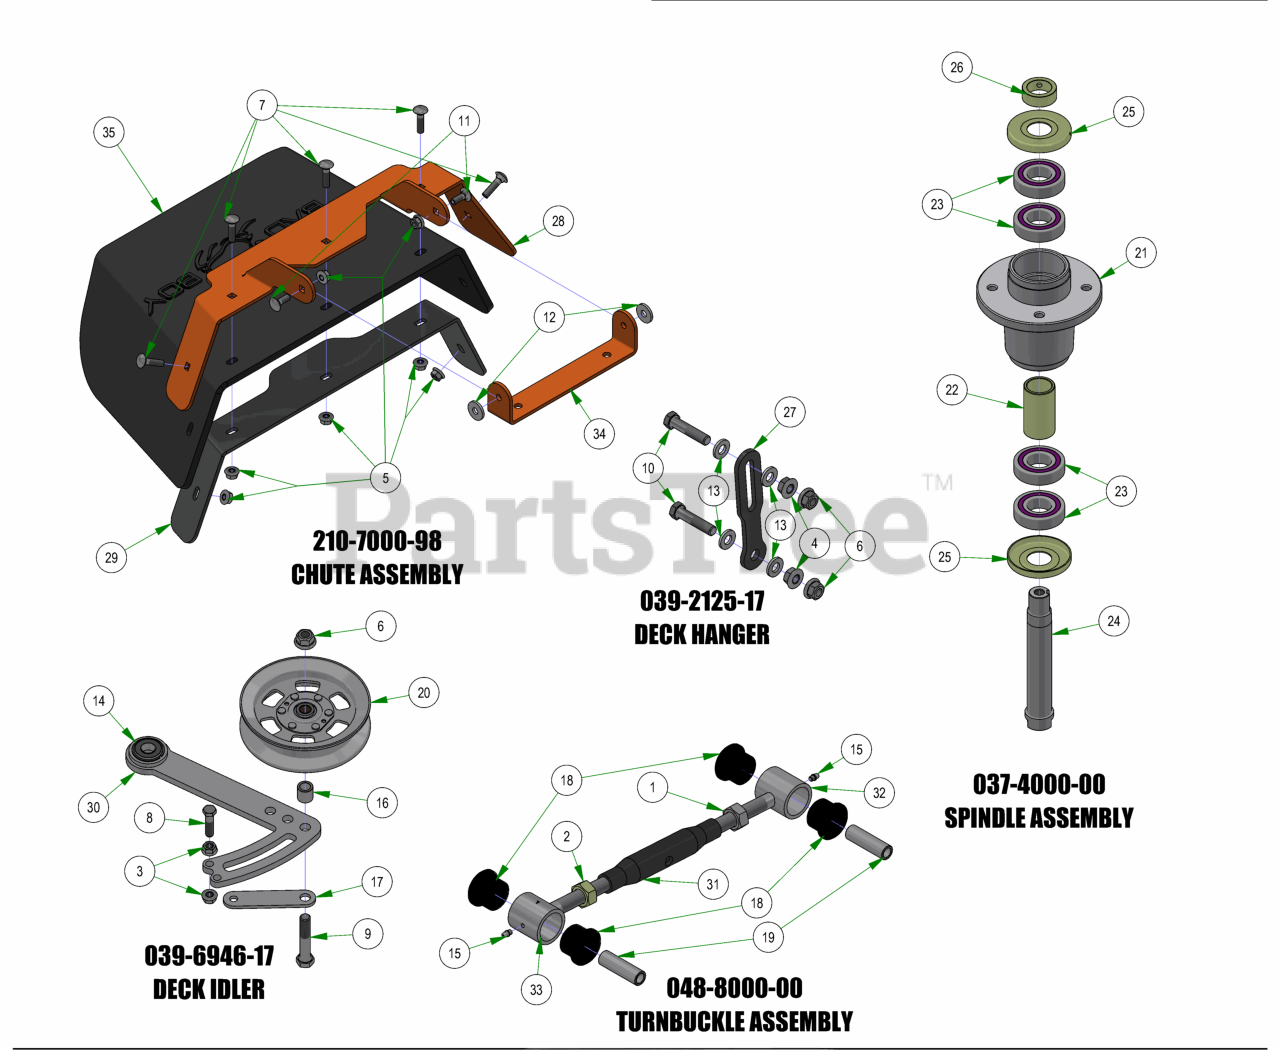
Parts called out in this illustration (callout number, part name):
1	Hex Nut M20-2.5
2	Hex Nut M20-2.5 Left Hand Threads Gold Plated
3	3/8-16 HEX SERRATED FLANGE NUT HARD/ZINC
4	1/2-13 HEX SERRATED FLANGE NUT HARD/ZINC
5	5/16-18 NYLON INSERT FLANGE LOCKNUT ZINC
6	1/2-13 NYLON INSERT FLANGE LOCKNUT ZINC
7	5/16-18 X 1-1/4 CARRIAGE BOLT ZINC
8	3/8-16 X 1-1/2 HEX CAP SCREW (GR.5) ZINC
9	1/2-13 X 2-3/4 HEX CAP SCREW (GR.5) ZINC
10	1/2-13 X 2-1/4 HEX CAP SCREW (GR.5) ZINC
11	5/16-18 X 7/8 CARRIAGE BOLT ZINC
12	.360 ID X .983 OD X .120 THICK FLAT WASHER NYLON
13	.505 ID X 1.000 OD X .125 THICK FLAT WASHER NYLON
14	Ball Bearing w/Retainer, 99502H-NR, .625 Bore x 1.375 OD x .4375 Width
15	1/4-28 Grease Fitting
16	.51 ID X .75 OD X .75 LGTH SOLID SPACER ZINC
17	Belt Tensioner Retainer Plate
18	Polyeurethane Bushing
20	5" Idler Pully
21	4000 Series Spindle Housing
22	4000 Series Spindle Spacer
23	Bearing - 6206
24	Spindle Shaft
25	Spindle Dust Cap
26	Locking Collar w/ 1/4"-20 Set Screw
27	Deck Hanger
28	2019 Upper Chute Bracket
29	2019 Lower Chute Bracket
30	2019 Deck Belt Tensioner
31	2024 Turnbuckle Body
32	Turnbuckle End Right-Handed Thread
33	Turnbuckle End Left-Handed Thread
34	2019 Chute Hanger
35	2019 Belted Chute with Logo
